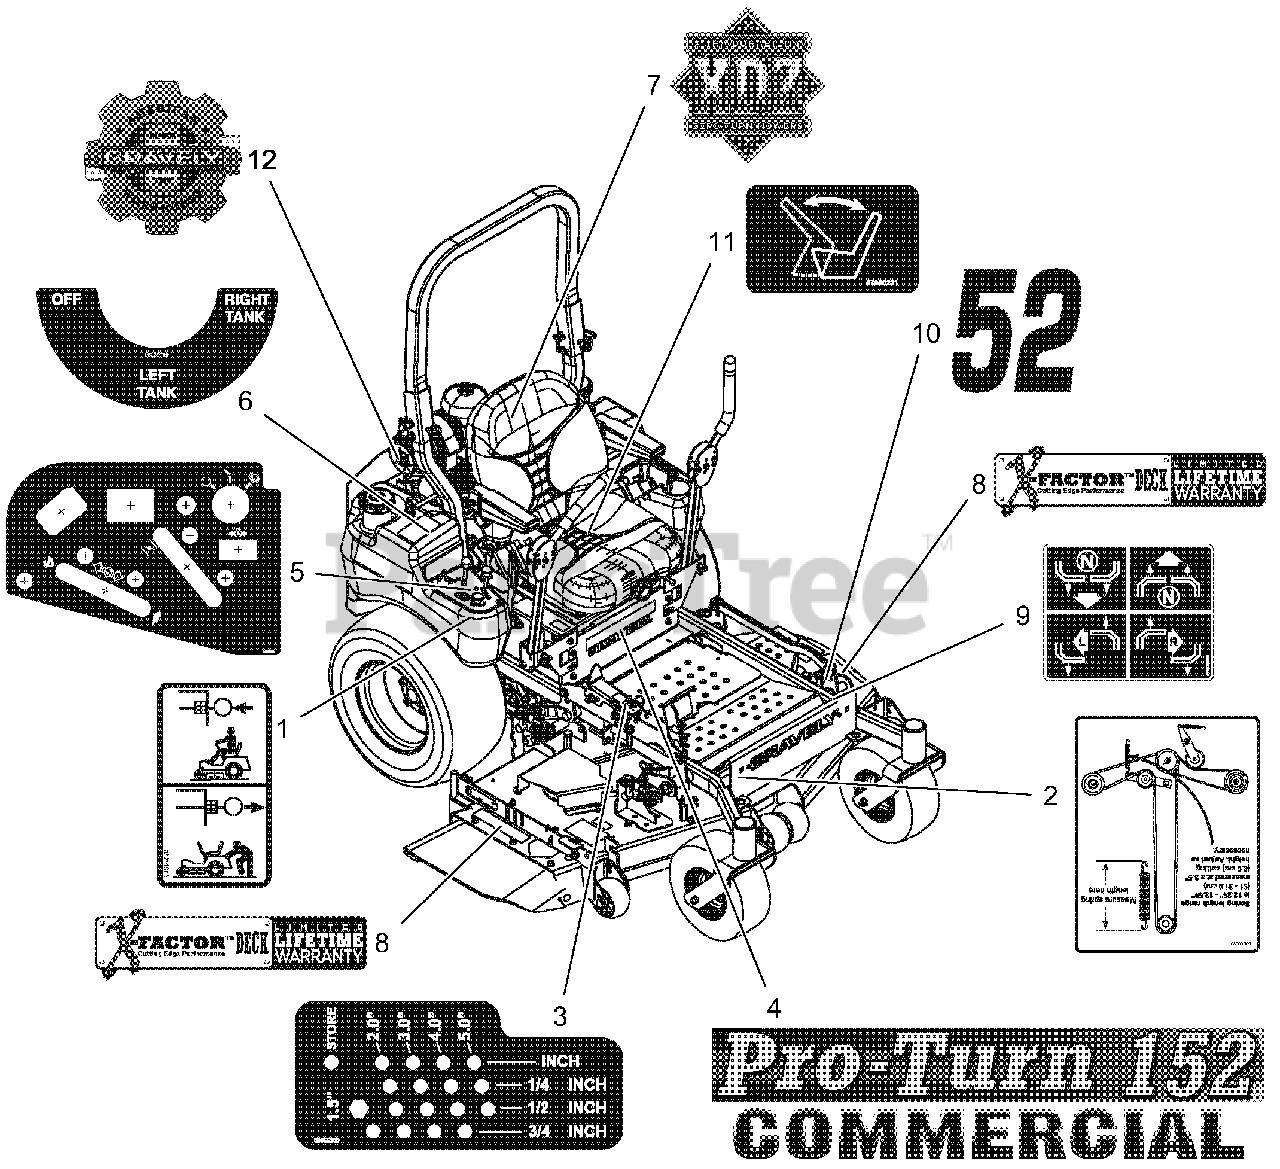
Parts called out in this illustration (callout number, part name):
1	DECAL, TRANSMISSION DISCONNECT
2	DECAL, BELT ROUTING
3	DECAL, HEIGHT OF CUT
4	DECAL, PRO-TURN 152
5	DECAL, CONTROL PANEL
6	DECAL, FUEL VALVE
7	DECAL, XDZ
8	DECAL, X-FACTOR DECK
9	DECAL, INSTRUCTIONAL - STEERING
10	DECAL, 52"
11	DECAL, SEAT RELEASE
12	DECAL, GRAVELY HERITAGE-LARGE
